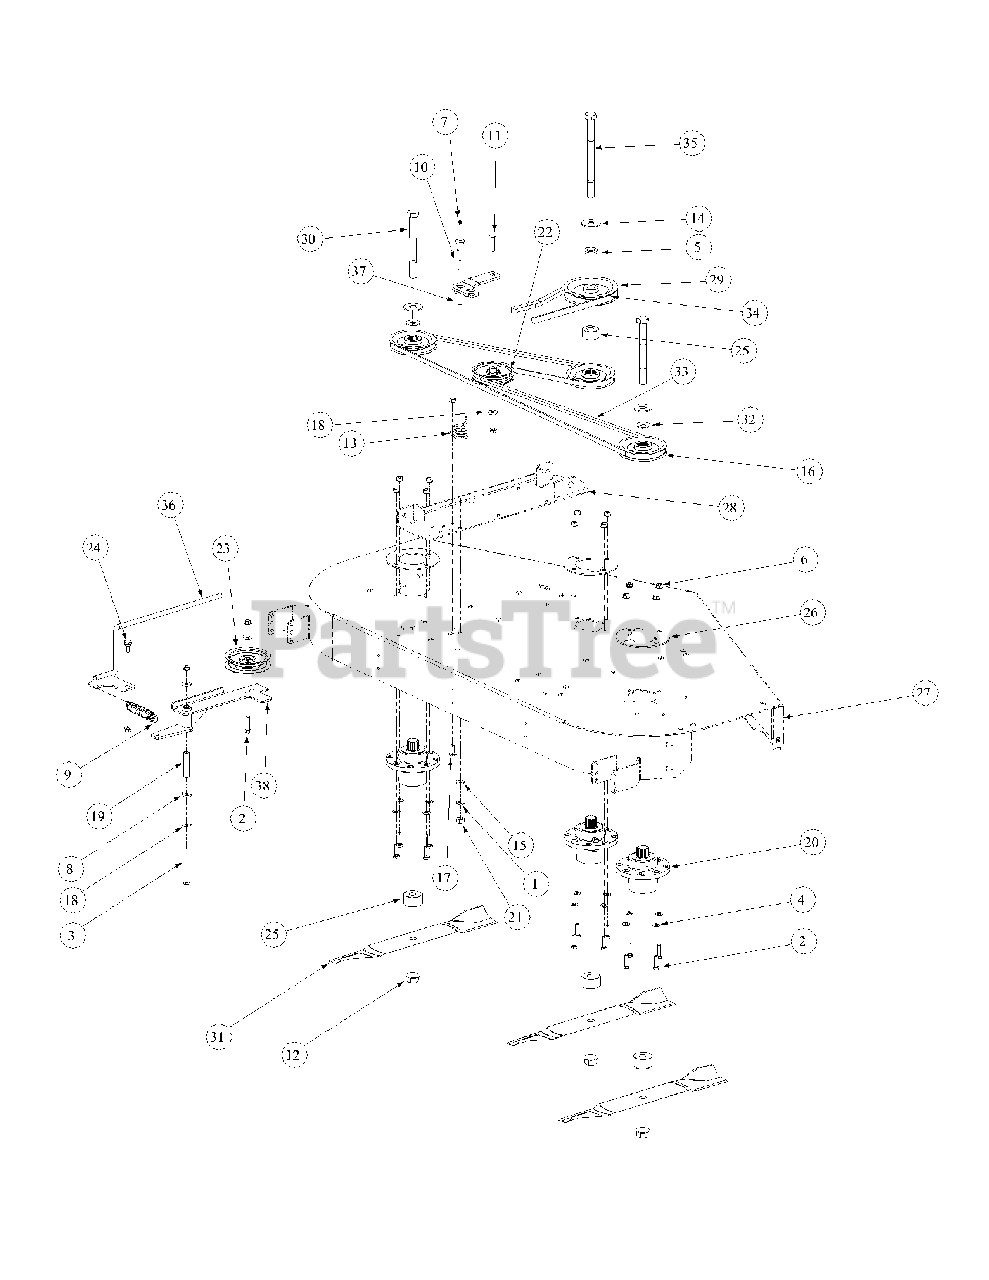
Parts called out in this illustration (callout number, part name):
1	Lock Washer, 7/16
2	Hex Cap Screw, 3/8-16 x 1-1/2
3	Hex Cap Screw, 3/8-16, 3.75
4	Flat Washer, 3/8
5	Caster Spacer
6	Flange Lock Hex Nut, 3/8-16
7	Grease Fitting, 1/4-28 x 3/16
8	Idler Washer
9	Extension Spring, 1.0 x OD x 5.125
10	Shoulder Screw, 7/16-14
11	Hex Carriage Screw, 3/8-16, 1.75
12	Flange Hex Nut, 3/4-16
13	Torsion Idler Spring
14	Flat Washer, .781 ID 2.00 OD, .105
15	Flat Washer, .469 ID, .875 OD, .105
16	V-Pulley, 4.65 OD
17	Carriage Bolt, 3/8-16 x 1
18	Flat Washer, .406 ID, 1.0 OD, .105
19	Spacer, .39 ID x .625 OD x 2.75
20	Aluminum Spindle Assembly
21	Hex Nut, 7/16-14
22	Flat Pulley
23	Idler Pulley, 4.06 OD
24	Shoulder Screw, .50 x .27 Lg., 3/8-16
25	Spacer, .760 ID x 2.00 OD x 1.1
26	Aluminum Spindle Support Plate
27	60 Deck Assembly
28	Left Hand Mount Deck Bracket Assembly
29	V-Pulley, 5.774 OD
30	Hex Cap Screw, 3/4-16, 7.00
31	Hi-Lift Blade, 21.0, 0.756 ID
32	Spacer .812 ID x .268 LG
33	V-Belt, A Section x 122.3
34	V-Belt, B Section x 91.2
35	Hex Cap Screw, 3/4-16, 9.00
36	Spring Tension Rod Assembly
37	Idler Arm Assembly, Deck Spindle
37	Bearing Sleeve
38	Idler Arm Assembly, Flat Top Bearing
38	Bearing Sleeve
